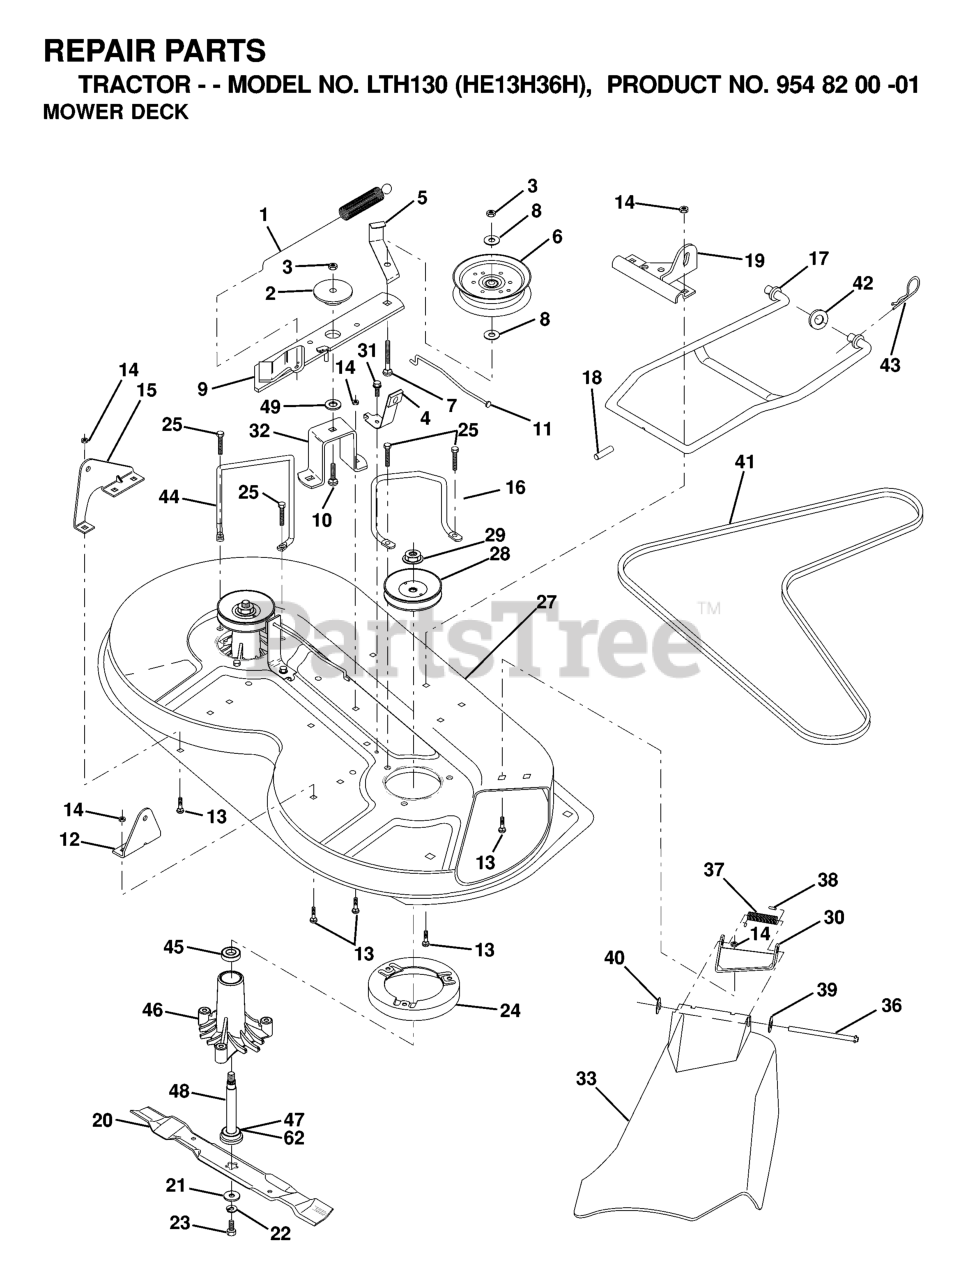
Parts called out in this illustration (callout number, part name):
1	42" DECK KIT
2	RP BOLT 5/16-18 X3/4 ZN/YEL GR
3	BRKT ASM SWAY BAR
4	BRACKET SWAY BAR 42" DECK
5	RETAINER-SPRNG RB
6	REAR SUSP ARM
8	BLADE BOLT
9	LOCKWASHER
10	WASHER.BLADE
11	BLADE 42", YTH 160
12	BEARING.BALL.#6204.(MANDREL)
13	SHAFT ASM VENT
14	HOUSING.MANDREL.VENTED (MACHD)
16	STRIPPER
18	BOLT
19	BOLT SHD 5/16-18
20	BAFFLE.VORTEX
21	LOCKNUT
22	STIFFENER BRACKET
23	DEFLECTOR BRACKET
24	CAP-SLEEVE LT
25	SPRING TORSION
26	NUT PUSH M
27	SHIELD DEFLECTOR
28	Washer 11/32 x 5/8 x 16 Ga SD
29	ROD.HINGE
30	SCREW THDROL ROLLING WASHER HD
31	WASHER
32	PULLEY/MANDREL
33	NUT
35	FASTENER.XMAS.TREE
36	FLAT IDLER PULLEY
37	WASHER
44	GUARD MANDREL LH BLACK
45	RETAINER M
46	SCREW.1/4-20X5/8
49	ROLLER ASSY
52	BOLT.SHOULDER.5/16-18
53	ARM
54	HARDENED WASHER
55	ARM IDLER 42" MOWER LT/YT
56	SPACER.RETAINER.MOWER
59	GUARD, BELT
67	KNOB T (3/8 HOLE)
90	BOLT
91	BRACKET LH (A)
92	NUT
93	Washer 1 17/32 X 7/8 X 16 Ga
94	NOSE ROLLER
95	BRACKET RH (B)
111	BRACKET WHEEL GAUGE LH 42" DK
112	BRACKET WHEEL GAUGE RH 42" DK
113	SCREW 5/16"
114	NUT
115	BOLT.CARR.5/16-18X1/2
116	BOLT M
117	WHEEL.GAUGE.STANDARD
118	LOCKNUT
119	WASHER.5/16.FLAT.STE.STD.
121	BRACKET.EXTRUDED.GAGE.WHEEL
128	WASHER FELT
129	WASHER
131	BOLT D
142	ARM SPRING BRAKE MOWER
143	BRACKET, ARM IDLER
144	DNO KEEPER.BELT.42".CLUTCH.CBL
145	PULLEY
146	BOLT, CARRIAGE IDLER
147	SPRING EXTENSION
148	IDLER RETURN SPRING
149	KIT CYLINDER #70331
151	BRACKET.CLUTCH.CABLE
152	CLUTCH CABLE 42"
153	WASHER FLAT 3/8"
154	SPRING RETAINER
155	SPRING RETENTION LEVER
156	SPACER.CLUTCH.CABLE
157	ROD CLUTCH CABLE 3/8"
158	SCREW LT
